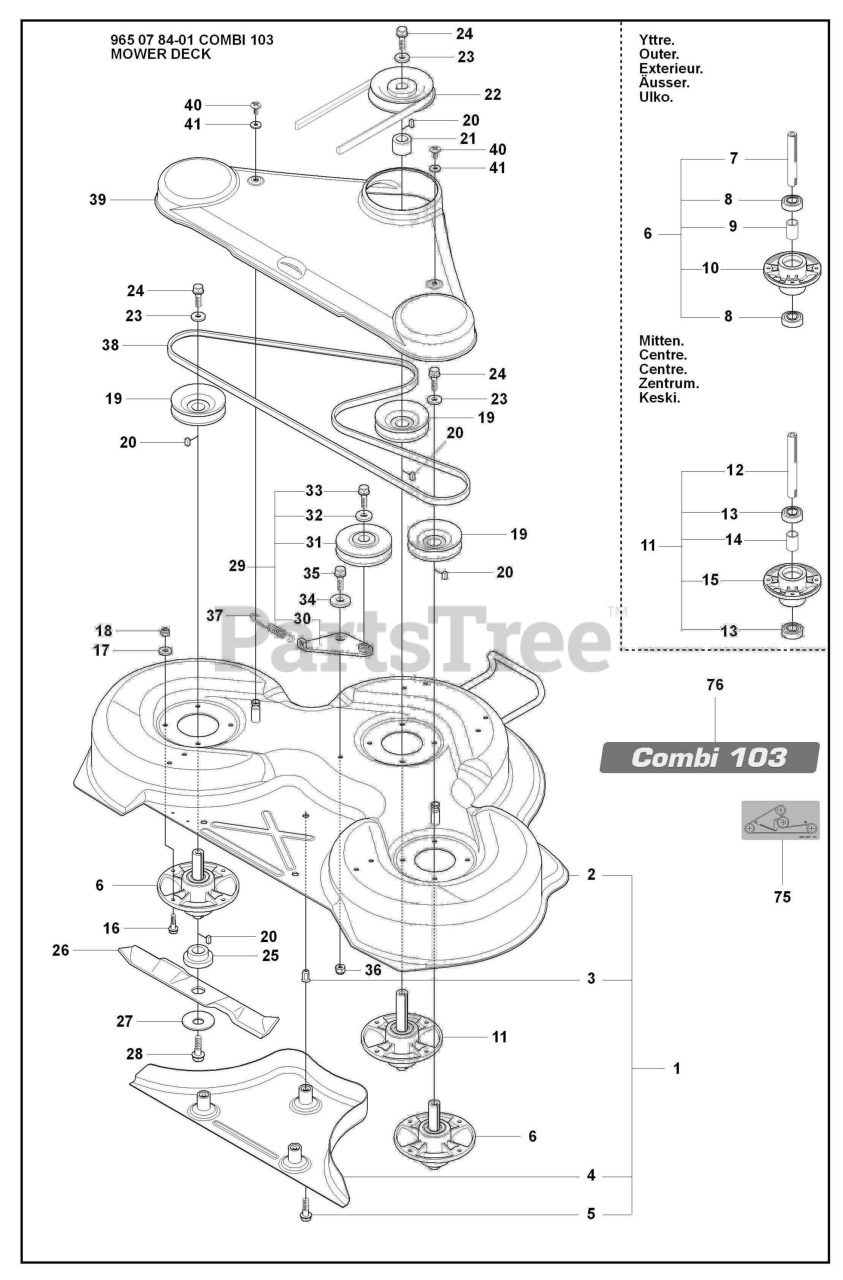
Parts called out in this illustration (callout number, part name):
1	CUTTING DECK
2	CUTTING DECK ASSY
6	RP SPINDLE ASSY
10	BEARING HOUSING
11	SPINDLE ASSY
15	BEARING HOUSING
17	WASHER BRB 8.4X17
18	LOCKNUT M8
26	BLADE
27	WASHER
29	BELT TENSIONER ASSY
30	BELT TENSIONING ARM
34	WASHER
36	LOCKNUT M8
38	BELT
